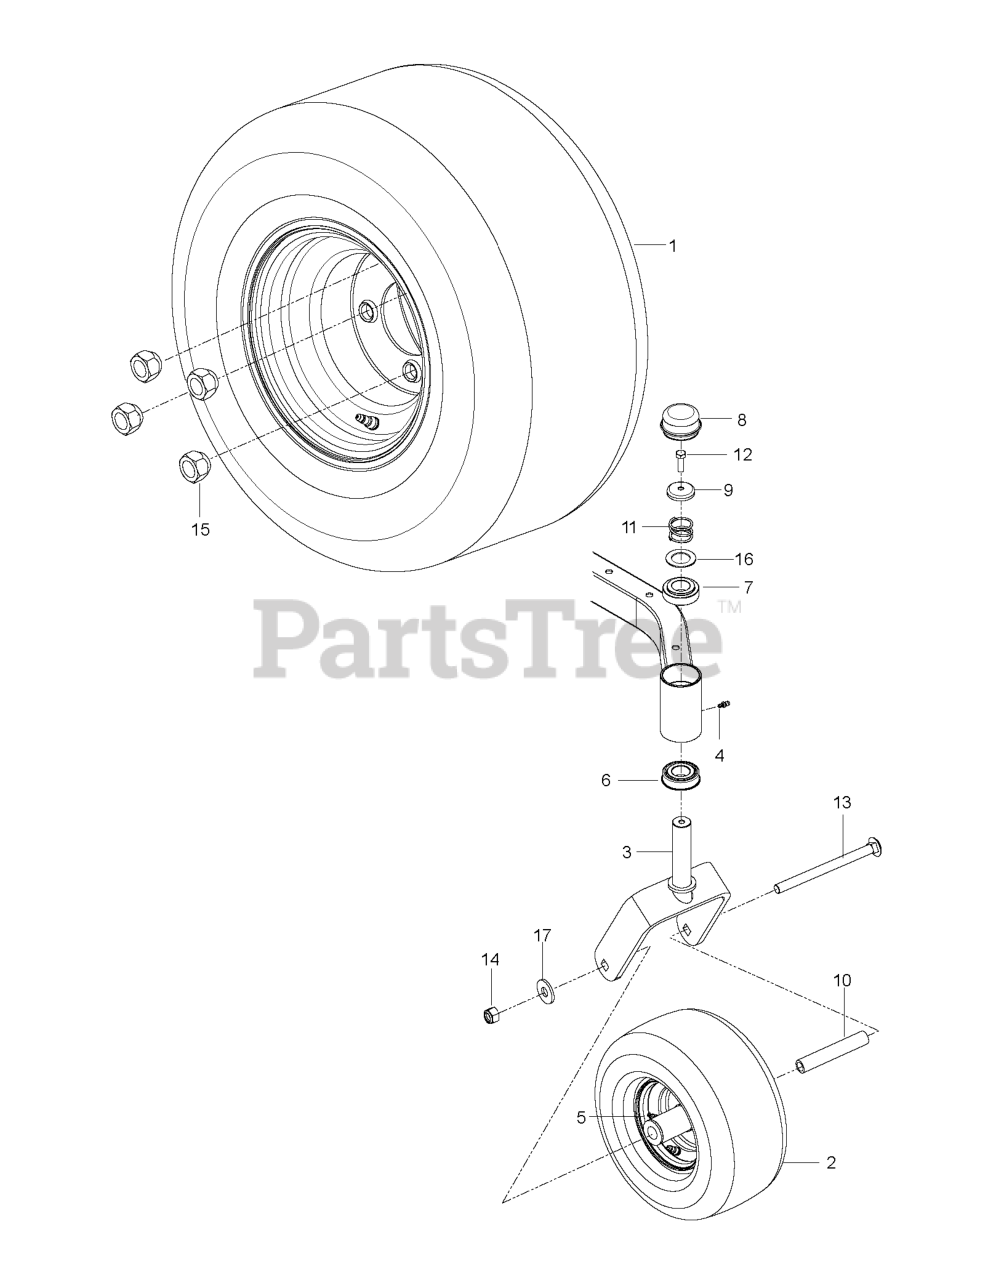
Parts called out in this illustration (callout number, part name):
1	WHEEL.CARLSTAR.18X8.5-8".MS417
2	WHEEL.CARLSTAR.11X4-5".MS417
3	YOKE.PNT.CASTER.ORG
4	ZERK, 3/16, DRIVE IN
5	ZERK
6	BEARING FLANGED
7	BUSHING, CASTER
8	GREASE CAP
9	CASTER.PLUG
10	SPACER.PIVOT
11	SPRING, CASTER
12	5/16-18X1 HHB G5W/NY
13	RHSNB 1/2-13 X 7.5
14	NUT. 1/2-13 HEX CNTRLK GR 5 ZD
15	NUT.1/2-20.UNF-2B.GR.8.YL
16	WASHER, 1.025 ID X 1.64
17	WASHER.9/16 X 1 3/8 X 12 GA.
